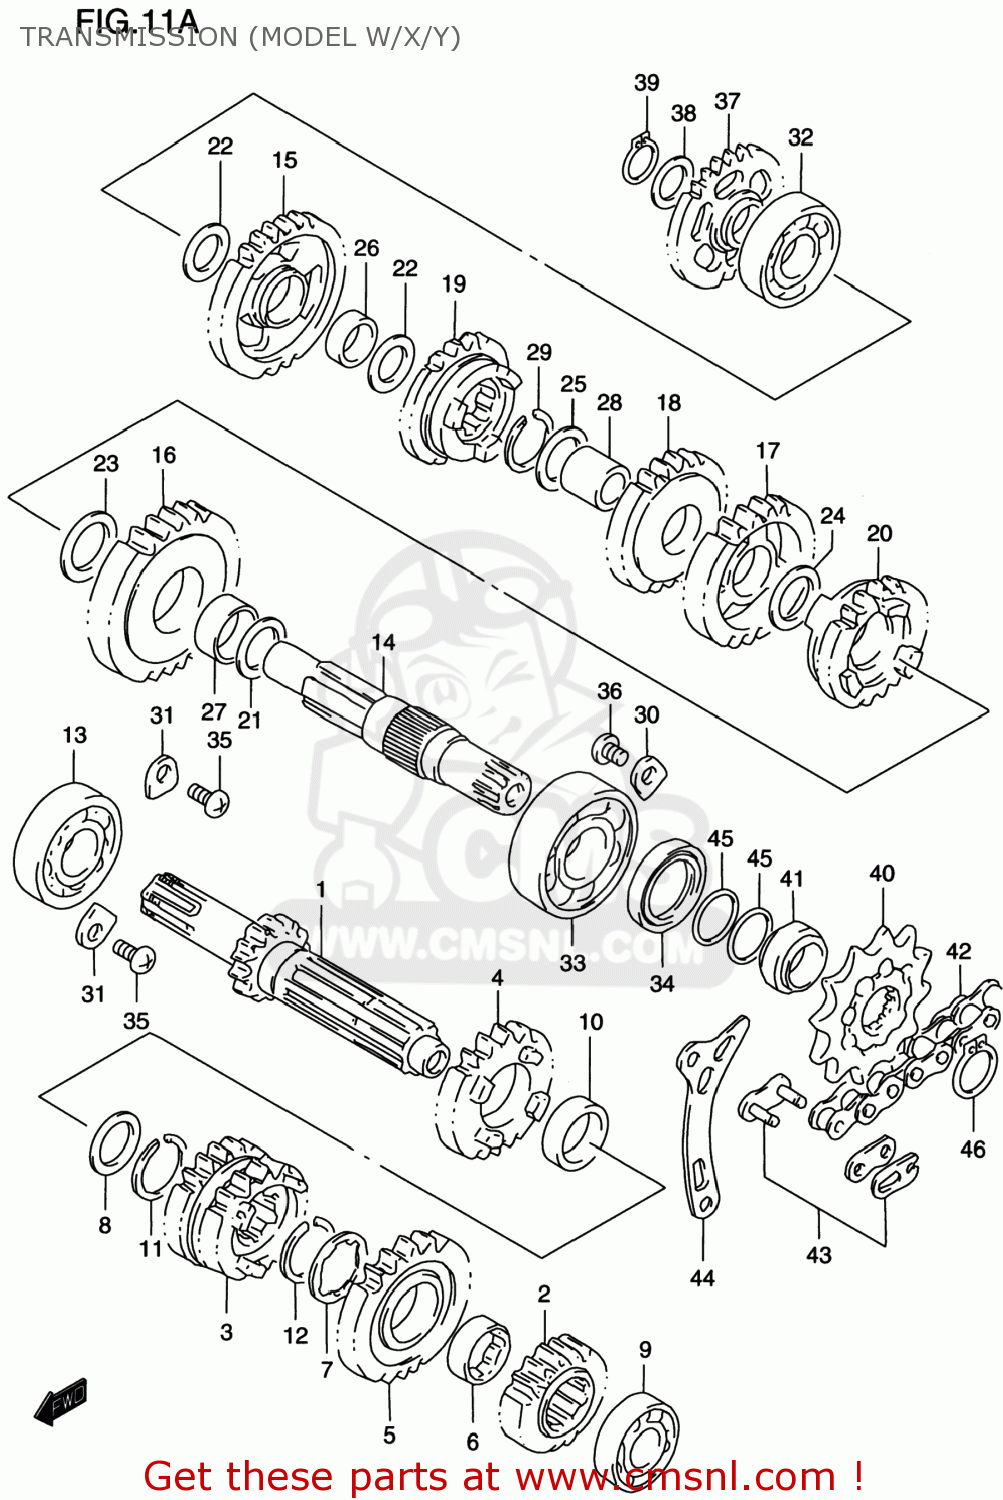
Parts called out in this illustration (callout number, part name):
1	SHAFT,COUNTER(NT:14)
2	GEAR,2ND DRIVE(NT:16)
3	GEAR,THIRD & FOURTH DRIVE,N
4	GEAR,5TH DRIVE(NT:19)
5	GEAR,SIXTH DRIVE (NT:20)
6	BUSH,6TH DRIVE GEAR
7	WASHER,LOCK
8	SHIM(22X28X1)
9	BEARING(20X47X12)
10	BUSH(22X26X9)
11	CIRCLIP
12	CIRCLIP
13	BEARING
14	SHAFT,DRIVE
15	GEAR,1ST DRIVEN(NT:30)
16	GEAR,2ND DRIVEN(NT:28)
17	GEAR,THIRD DRIVEN (NT:26)
18	GEAR,4TH DRIVEN(NT:24)
19	GEAR,5TH DRIVEN(NT:20)
20	GEAR,SIXTH DRIVEN (NT:19)
21	WASHER(20X30X3)
22	SHIM(17X26X1)
23	SHIM(22X30X1)
24	SHIM(22X30X1)
25	SHIM(22X30X1)
26	BUSH(17X20X9)
27	BUSH(22X26X9)
28	BUSH(22X25X18)
29	CIRCLIP
30	RETAINER,COUNTER BEARING,R
31	RETAINER
32	BEARING(17X40X9.5)
33	BEARING(20X52X12.5)
34	SEAL,OIL(28X38X6)
35	SCREW
36	SCREW
37	GEAR,KICK STARTER IDLE
38	SHIM(17X24X0.5)
39	CIRCLIP,17MM
40	SPROCKET,ENGINE
41	SPACER,ENGINE SPROCKET
42	CHAIN ASSEMBLY DID520DM.11
43	JOINT SET,CHAIN
44	PLATE,FR CHAIN GUIDE
45	O RING(D:1.9,ID:19.8)
46	CIRCLIP
